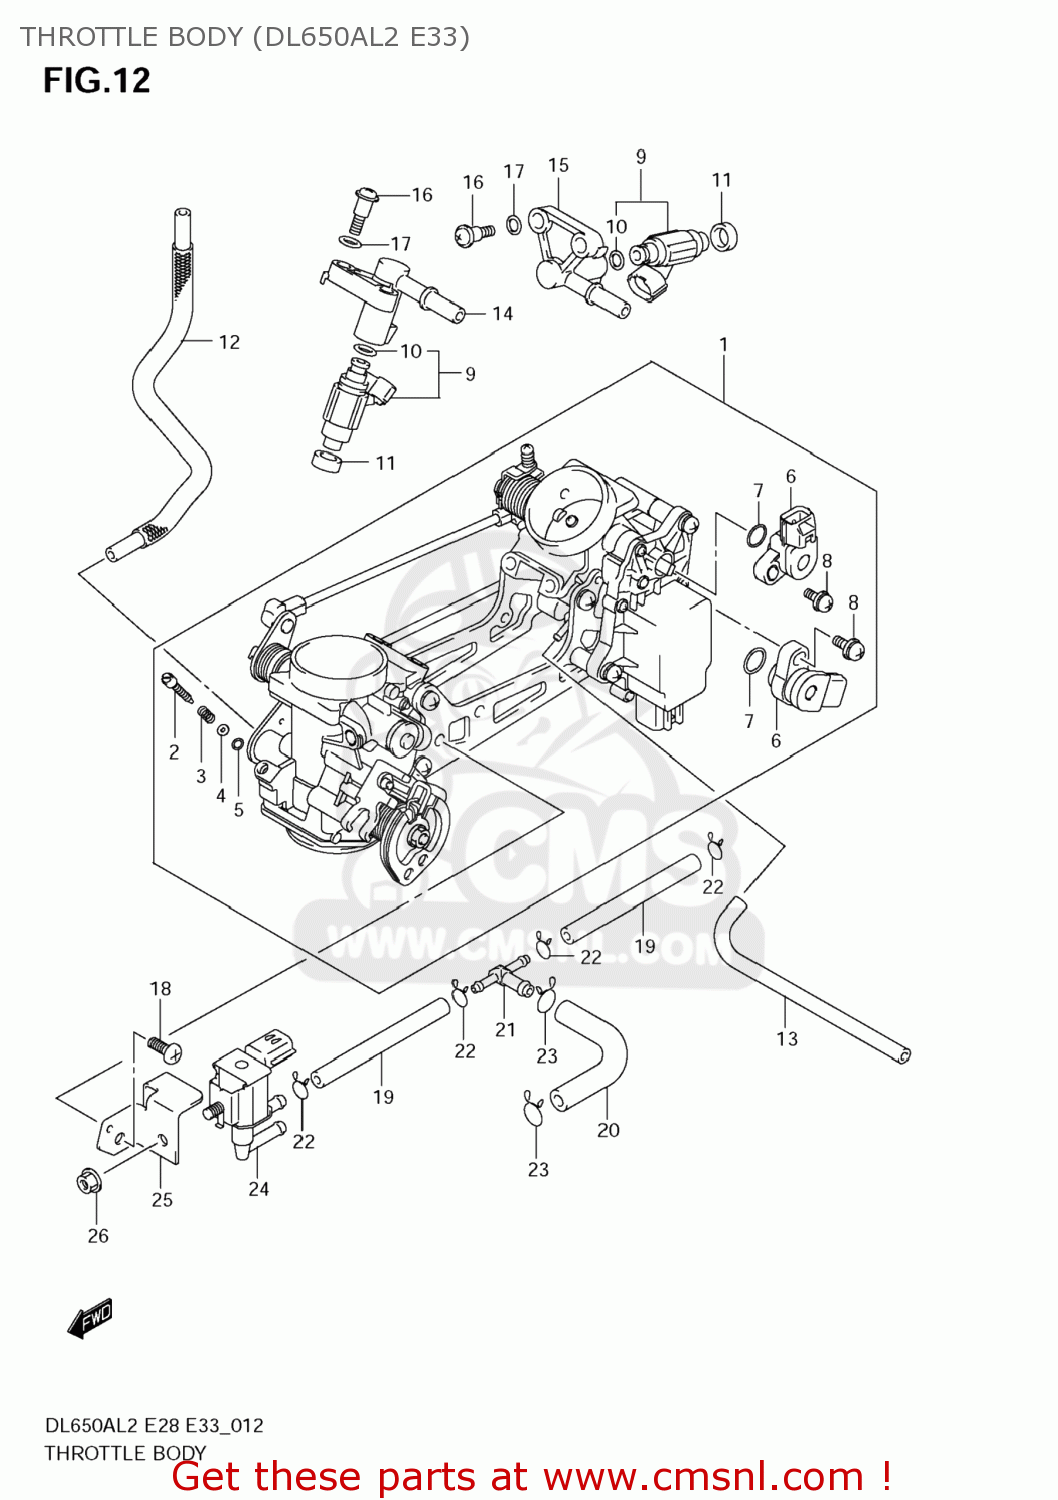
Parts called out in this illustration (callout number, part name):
1	BODY ASSY,THROTTLE
2	SCREW
3	SPRING,THROTTLE SCREW
4	WASHER
5	O RING,PILOT AIR SCREW
6	SENSOR
7	O RING
8	SCREW
9	INJECTOR ASSY
10	O-RING
11	SEAL
12	HOSE
13	HOSE
14	DELIVERY PIPE
15	DELIVERY PIPE
16	SCREW
17	PACKING (NAS)
18	SCREW
19	HOSE
20	HOSE
21	NIPPLE
22	CLIP
23	CLIP
24	VALVE,CANISTER PURGE
25	BRACKET
26	NUT
